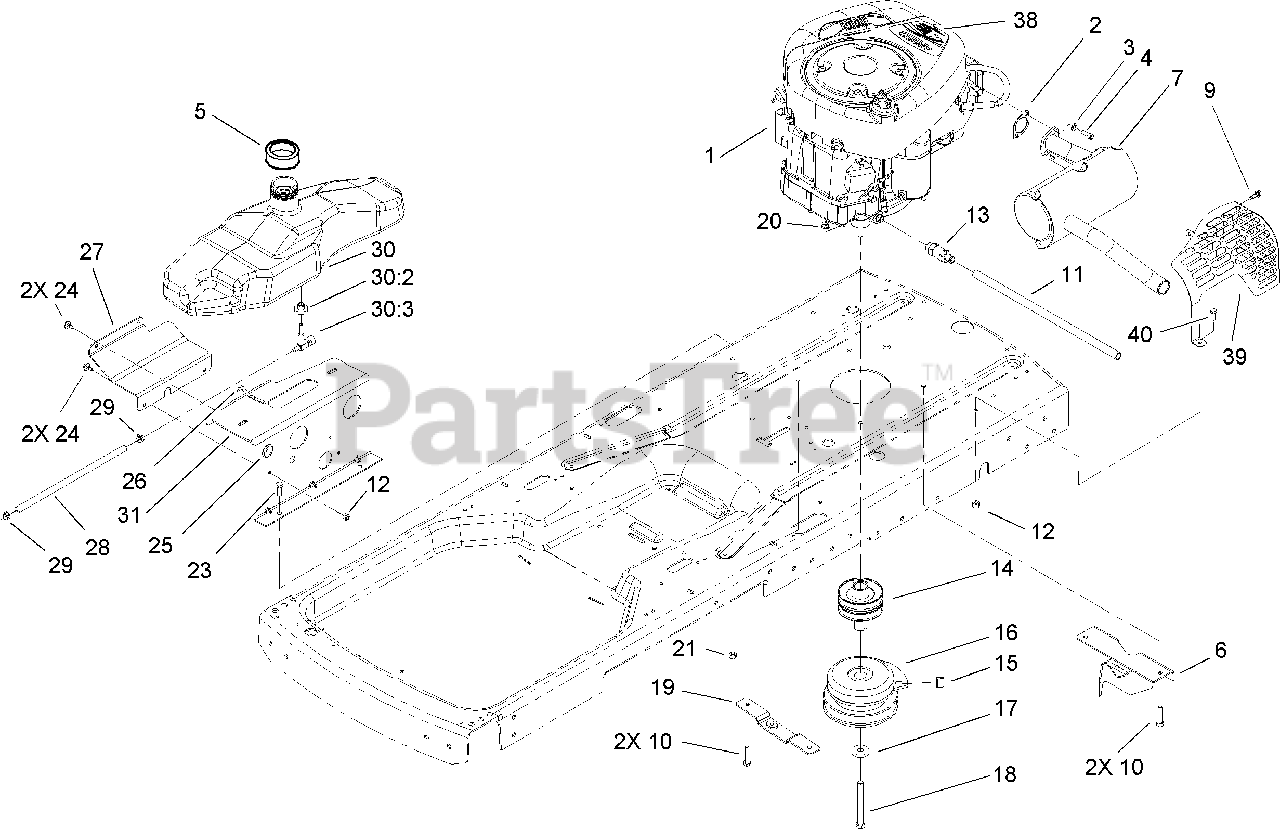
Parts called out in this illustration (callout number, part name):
2	GASKET-MUFFLER
3	WASHER-LOCK
4	SCREW-HSH
5	SEAL-FOAM
6	BRACKET-PIVOT
9	SCREW-HWH
10	SCREW-HH
11	TUBE-DRAIN, OIL
12	NUT-LOCK, NI
13	VALVE-DRAIN, OIL
14	PULLEY-ENGINE
16	CLUTCH-ELECTRIC
18	SCREW-HH
19	PLATE-MOUNT, IDLER
21	NUT-LOCK, NI
23	SCREW-HH
24	SCREW-HHF
27	PLATE-SUPPORT
28	HOSE-FUEL
30	FUEL TANK ASM
30:3	VALVE-FUEL
38	DECAL-ENGINE
39	GUARD-MUFFLER
40	SCREW-HH
